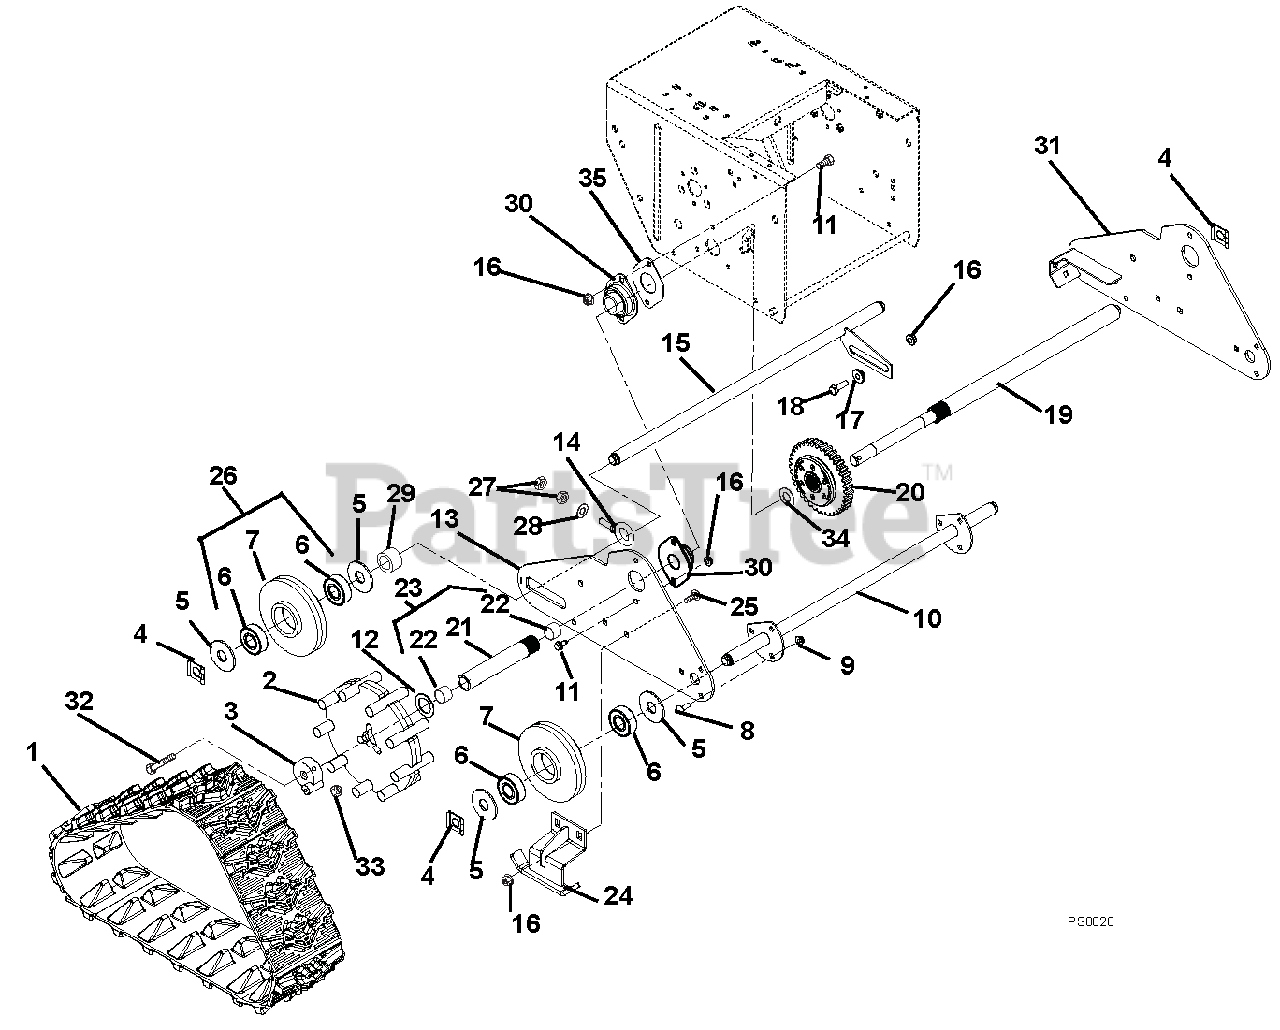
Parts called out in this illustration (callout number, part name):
1	TRACK, RUBBER
2	WHEEL, DRIVE-TRACK
3	HUB, LOCKOUT-ASSEMBLY
4	CLIP, SNAP .625 DIA
5	WSHR-FL-STL .755X2.000X.125 YZ
6	BRG-BALL .750X1.781X.61
7	WHEEL, BOGIE-TRACK
8	@BLT-RDHDSQNK .25-20X.75 G5YZ
9	@NUT-LK-TOP-FLG .25-20 YWZC
10	AXLE, FRONT
11	@BLT-HEX .31-18X.75 GR5 YWZC
12	WSHR-FL-STL 1.010X1.505X.062YZ
13	SIDE PLATE, RH-TRACK
14	BOLT, EYE
15	AXLE, BACK
16	@NUT-LK-TOP-FLG .31-18 YWZC
17	BSHG-FLG .32X.500X.344X.880
18	@BLT-HEX .31-18X1.00 GR5 YWZC
19	AXLE, LONG-TRACK DIFFERENTIAL
20	DIFFERENTIAL, AXLE LOCK
21	AXLE, SHORT-TRACK DIFFERENTIAL
22	BSHG-SLV .706X.764X.75 BRZ
23	AXLE, SHORT-TRACK W/BUSHINGS
24	RUNNER, GUIDE-TRACK
25	@BLT-RDHDSQNK .31-18X.75 G5YZ
26	WHEEL, BOGGIE-W/BEARINGS
27	@NUT-HEX .31-18 YWZC
28	@WSHR-FL-STL.344X.688X.065YWZC
29	BSHG-SLV .766 X 1.125 X .500
30	BEARING, FLANGE-1.004/1.000"ID
31	SIDE PLATE, LH-TRACK
32	@BLT-HEX .25-20X2.00 GR5 YWZC
33	@NUT-LK-CTR .25-20 YWZC
34	WSHR-FL-NY 1.38X2.00X.25
